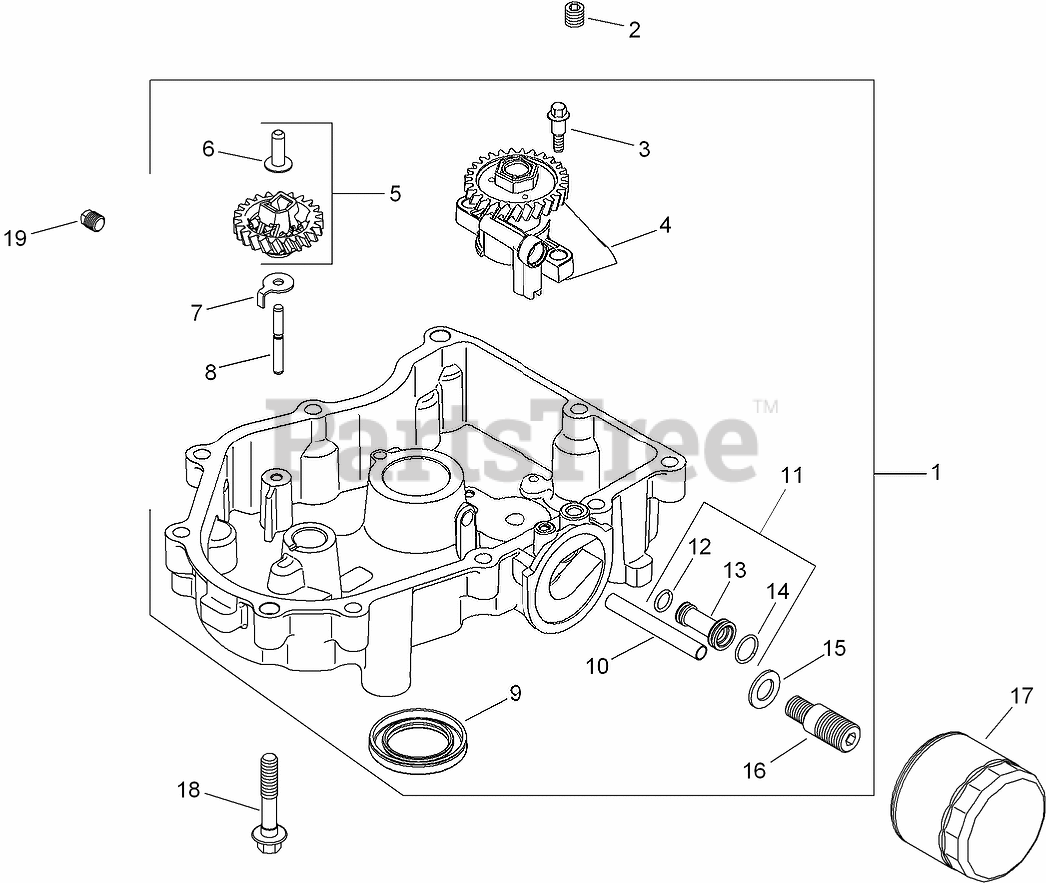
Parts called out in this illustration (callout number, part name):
1	OIL PAN ASM (INCLUDES 3-16)
2	PLUG-PIPE, COUNTERSUNK (1/8)
3	SCREW-SHOULDER, THD FRM (M6x1.0x26.5)
4	OIL PUMP ASM
5	GOVERNOR GEAR W/PIN KIT
6	PIN-REGULATING, GOVERNOR
7	TAB-LOCKING
8	SHAFT-GEAR, GOVERNOR
9	SEAL-OIL
10	TUBE-FEED, OIL (FILTER TO PAN)
11	OIL FEED TUBE ASM (INCLUDES 12-14)
12	O-RING
13	TUBE-FEED, OIL
14	O-RING (OIL FILTER ADAPTER)
15	WASHER-FLAT
16	NIPPLE-FILTER, OIL
17	FILTER-OIL
18	SCREW-FLANGE (M8X1.25X45)
19	PLUG-PIPE, SQ HD (3/8)
